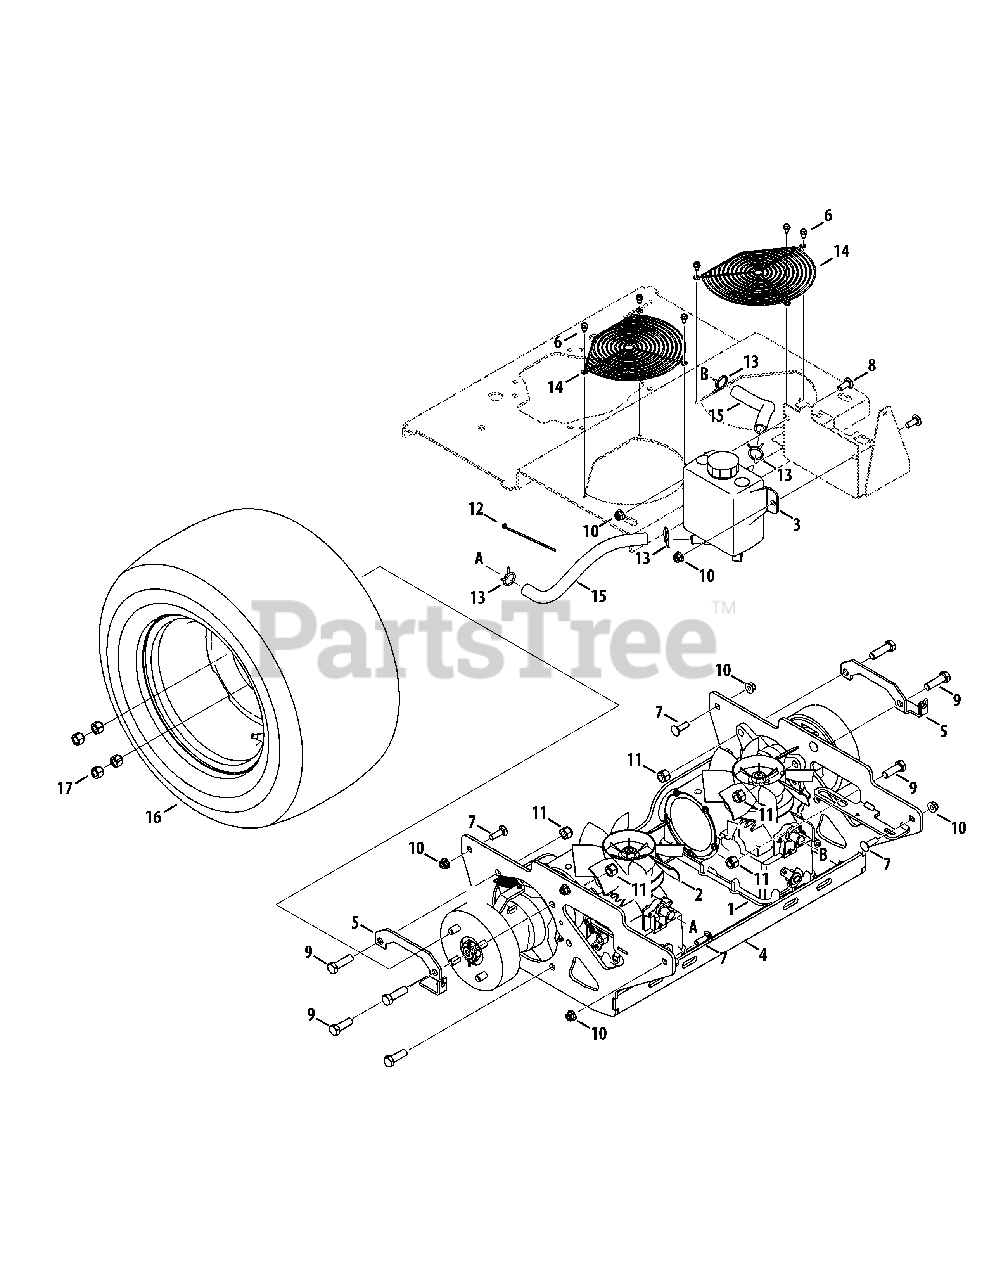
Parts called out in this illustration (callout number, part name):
1	Transmission, LH
2	Transmission, RH
3	Hydro Tank Assembly
4	Transmission Bracket Assembly
5	Transmission Brake Bracket
6	Screw, 10-24 x .500
7	Carriage Bolt, 3/8-16 x 1.25
8	Carriage Bolt, 3/8-16 x 1.00
9	Hex Cap Screw, 1/2-13 x 1.50
10	Nut, 3/8-16, Flangelock
11	Nut, 1/2-13, Flangelock
12	Cable Tie
13	Hose Clamp, .875
15	Hose, 5/8 ID x 12.00 LG
16	Wheel Assembly, 24 x 9.5-12 (48")
16	Wheel Assembly, 24 x 12-12 (54" & 60")
17	Lug Nut, 1/2-13
